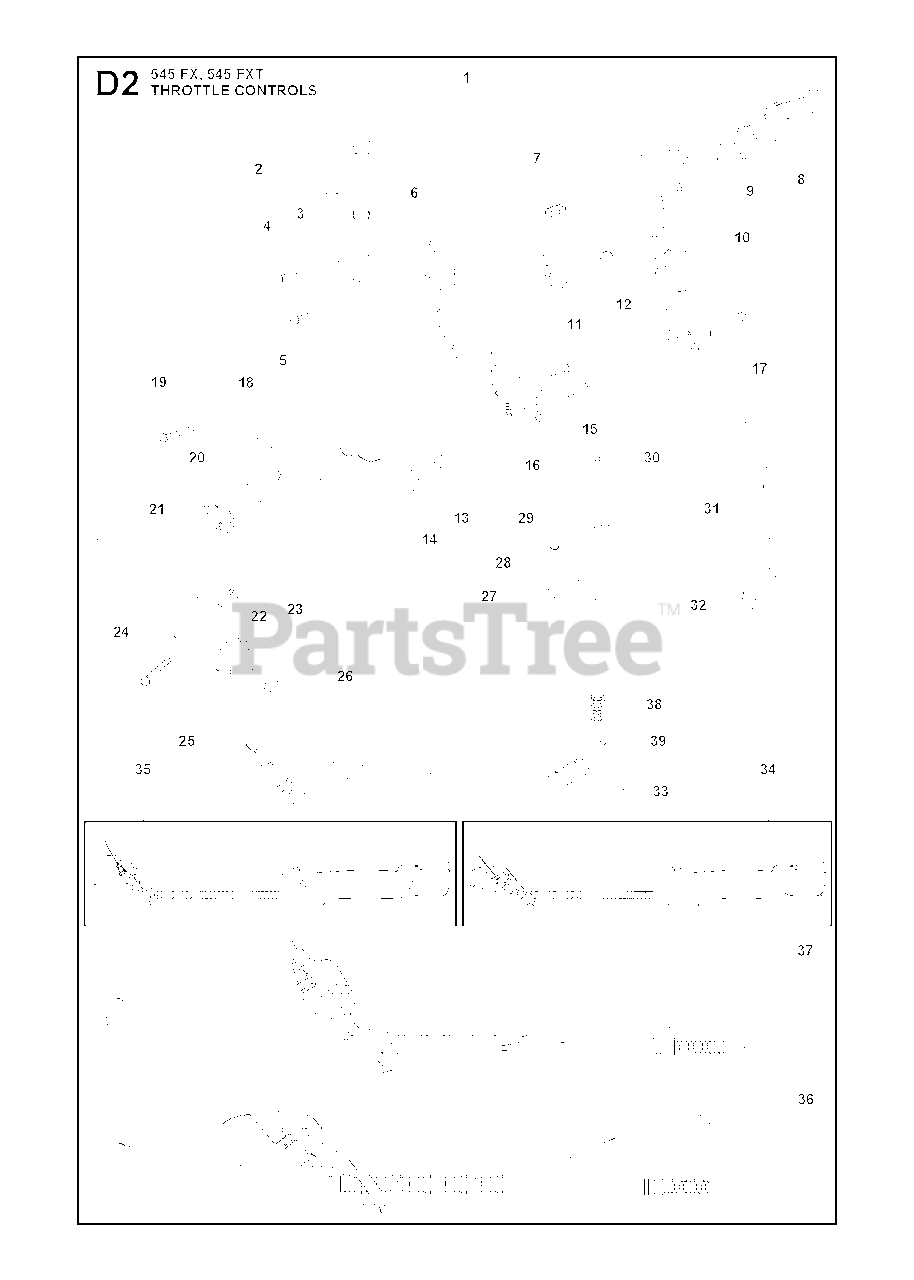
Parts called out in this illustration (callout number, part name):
1	THROTTLE HANDLE
2	THROTTLE TRIGGER
3	RP SPRING
4	SCREW
5	HANDLE
6	THROTTLE LOCK
7	SPRING
8	COVER
9	STOP BUTTON
10	HANDLE
11	LEVER
12	SPRING
13	SCREW
14	HOLDER
15	SCREW
16	HOLDER
17	NUT M6M M5
18	HOLDER
19	SCREW
20	SWITCH (G)
22	NUT M6M M5
25	HEATING ELEMENT
26	RP HANDLE
26	%HANDLE
27	HANDLE HOLDER UPPER
31	HEATING ELEMENT
32	HOLDER
33	HANDLE HOLDER LOWER
34	THROTTLE HANDLE ASSY HVA
36	WIRING ASSY
